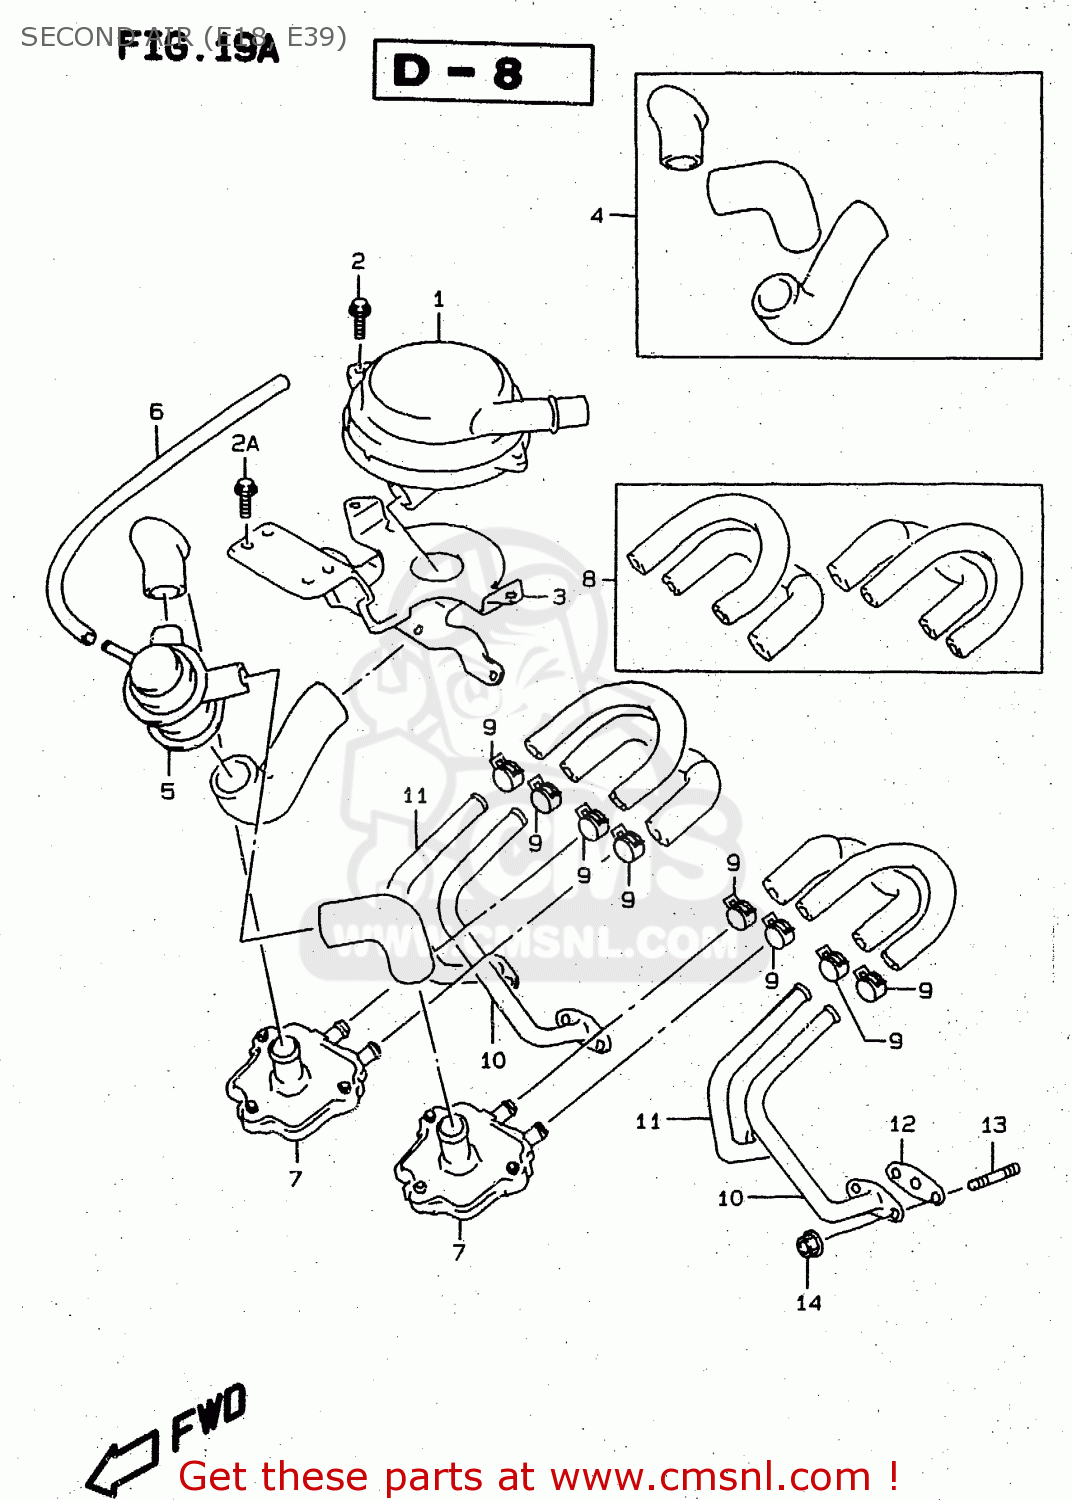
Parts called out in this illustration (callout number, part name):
1	CLEANER ASSEMBLY,SECOND AIR
2	BOLT
2A	BOLT
3	BRACKET COMP,SECOND AIR
4	HOSE SET,2ND AIR NO.2
5	VALVE ASSEMBLY,SECOND AIR SWITCH
6	HOSE(4.5X8.5X600)
7	VALVE ASSY,2ND AIR REED
8	HOSE SET,2ND AIR NO.1
9	CLIP
10	PIPE COMP,SECOND AIR NO.1
11	PIPE COMP,SECOND AIR NO.2
12	GASKET,SECOND AIR PIPE (N (NAS)
13	STUD BOLT
14	NUT
